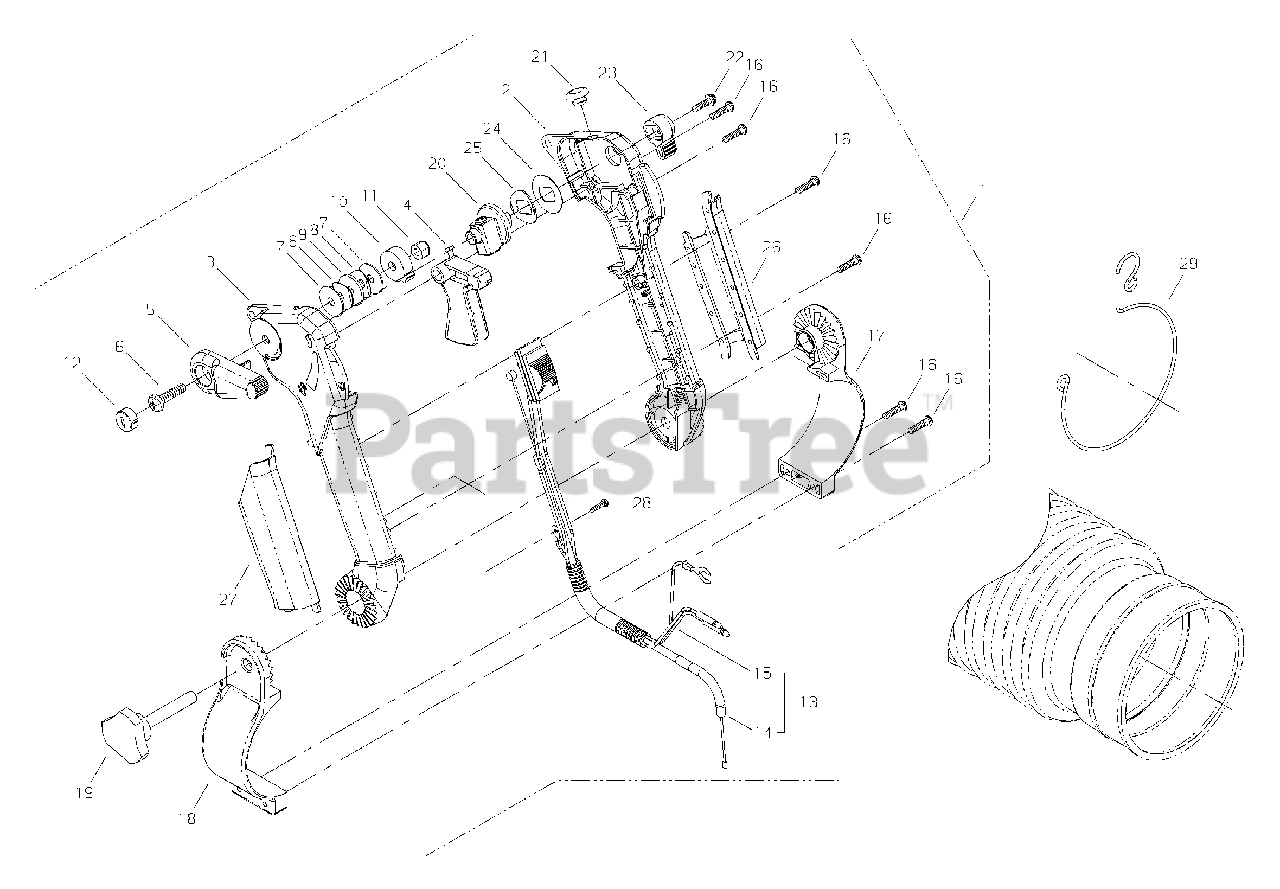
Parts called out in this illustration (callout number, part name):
1	THROTTLE LEVER ASSY
2	HANDLE, CONTROL - RIGHT
3	HANDLE, CONTROL - LEFT
4	TRIGGER, THROTTLE
5	LEVER, LOCK
6	ADJUSTABLE BOLT
7	WASHER - 6
8	LOCKWASHER
9	WASHER - 6
10	PLATE
11	NUT - 6 -- NYLON
12	CRUISE CONTROL BOLT CAP
13	THROTTLE CONTROL ASSY
14	CABLE, THROTTLE
15	SWITCH, IGNITION
16	SCREW
17	BRACKET, HANDLE - RIGHT
18	BRACKET, HANDLE - LEFT
19	KNOB, FASTENER
20	ADJUSTER ASSY
21	PLUG
22	SCREW, METERING LEVER PIN
23	SCREW, METERING LEVER PIN
24	WASHER
25	WASHER - SPRING
26	GRIP - RIGHT
27	GRIP - LEFT
28	SCREW
29	CLAMP
